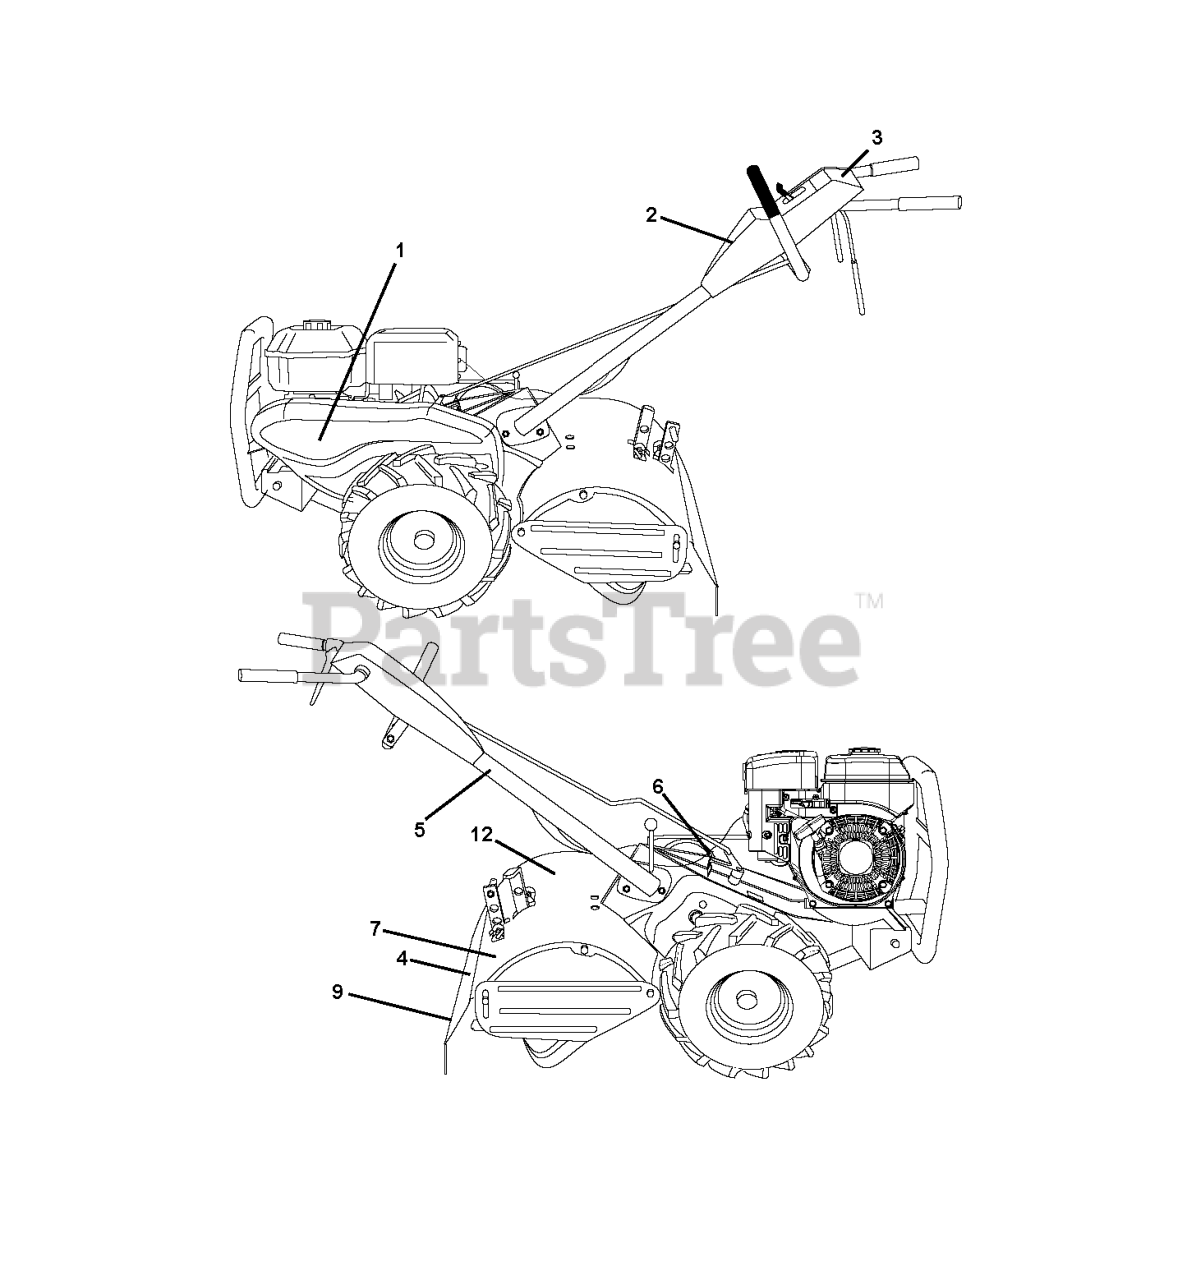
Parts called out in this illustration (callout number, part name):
1	RP.DECAL.BADGE.170MM.TEXTLOGO
3	DECAL.TILLER.CNSL.INS.
4	DECAL.SHIELD.TN.DRT.REAR.SY
5	DECAL.PLACEMENT.HAND.SYMBOLS
6	DECAL.SHIFT.INDICATOR.DRT
9	DECAL.WARNING.4-SYM.TILLER.INT
